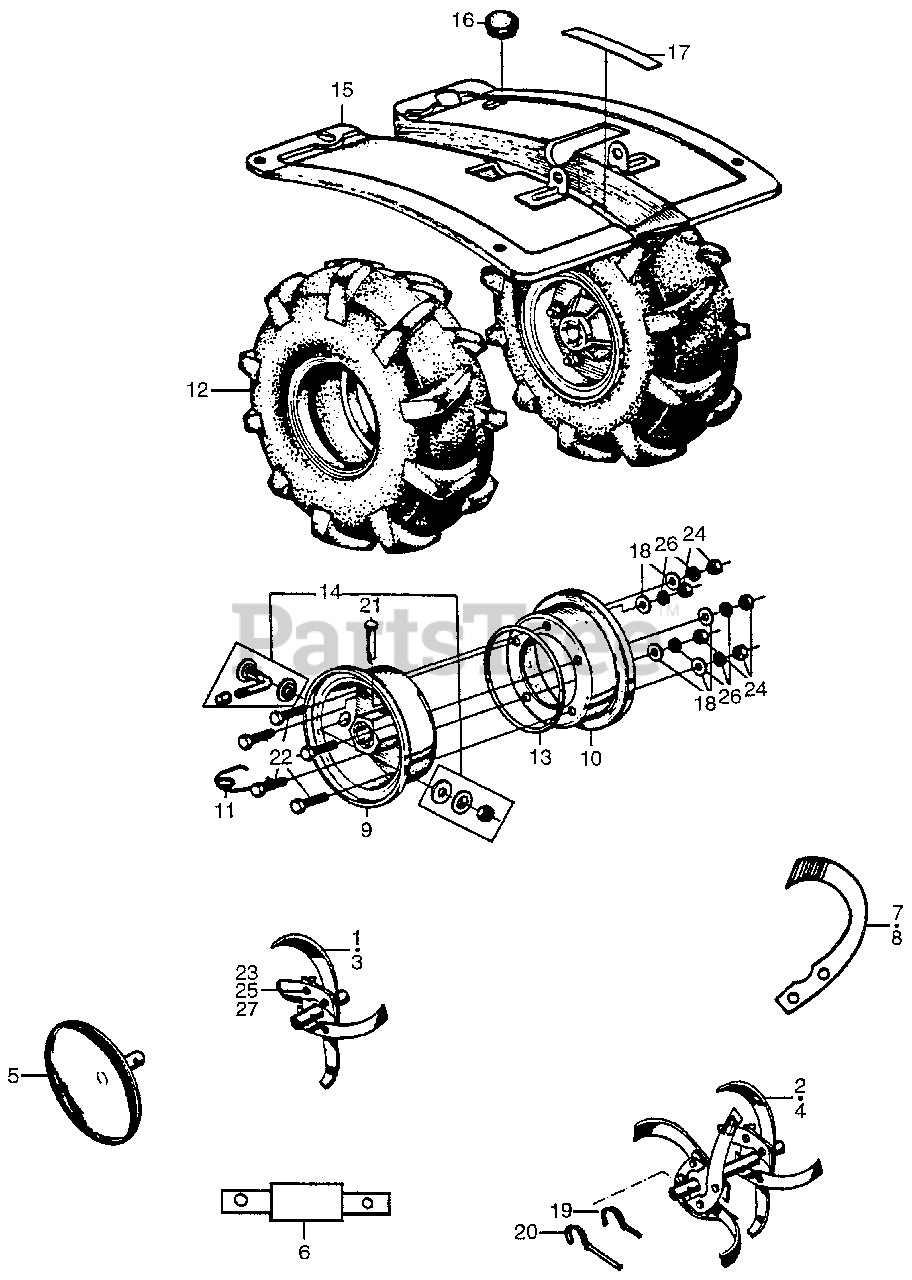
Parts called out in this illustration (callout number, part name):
1	TINE ASSY., R. SINGLE (NOT AVAILABLE)
2	TINE ASSY., R. DOUBLE
3	TINE ASSY., L. SINGLE (NOT AVAILABLE)
4	TINE ASSY., L. DOUBLE
5	DISK, TILLER
6	SHAFT, EXTENSION (NOT AVAILABLE)
7	BLADE, R. TINE
8	BLADE, L. TINE
9	RIM A, WHEEL *NH31* (MCKINLEY WHITE) (NOT AVAILABLE)
9	RIM A, WHEEL *NH31*
10	RIM B, WHEEL *NH31* (MCKINLEY WHITE)
11	CLIP, WHEEL
12	TIRE (3.50-5)
13	GASKET, RUBBER (NOT AVAILABLE)
14	TUBE BULB ASSY.
15	FENDER *NH31* (MCKINLEY WHITE)
16	STOPPER, TENSIONER ARM
17	MARK, OIL CHECK (NOT AVAILABLE)
18	WASHER (6X17)
19	CLIP, PIN (31MM)
20	CLIP PIN (33MM) (NOT AVAILABLE)
21	PIN A, WHEEL
22	BOLT, HEX. (6X16)
23	BOLT, HEX. (8X25)
24	NUT, HEX. (6MM)
25	NUT, HEX. (8MM)
26	WASHER, SPRING (6MM)
27	WASHER, SPRING (8MM)
NI	TINE ASSY. (NOT AVAILABLE)
NI	WHEEL ASSY. (NOT AVAILABLE)
NI	RIM A, WHEEL *NH31* (MCKINLEY WHITE)
NI	WEIGHT, FR. MAIN *R8*
NI	WEIGHT, FR. SUB *R8*
NI	SUB-FENDER, R. *NH31*
NI	SUB-FENDER, L. *NH31*
